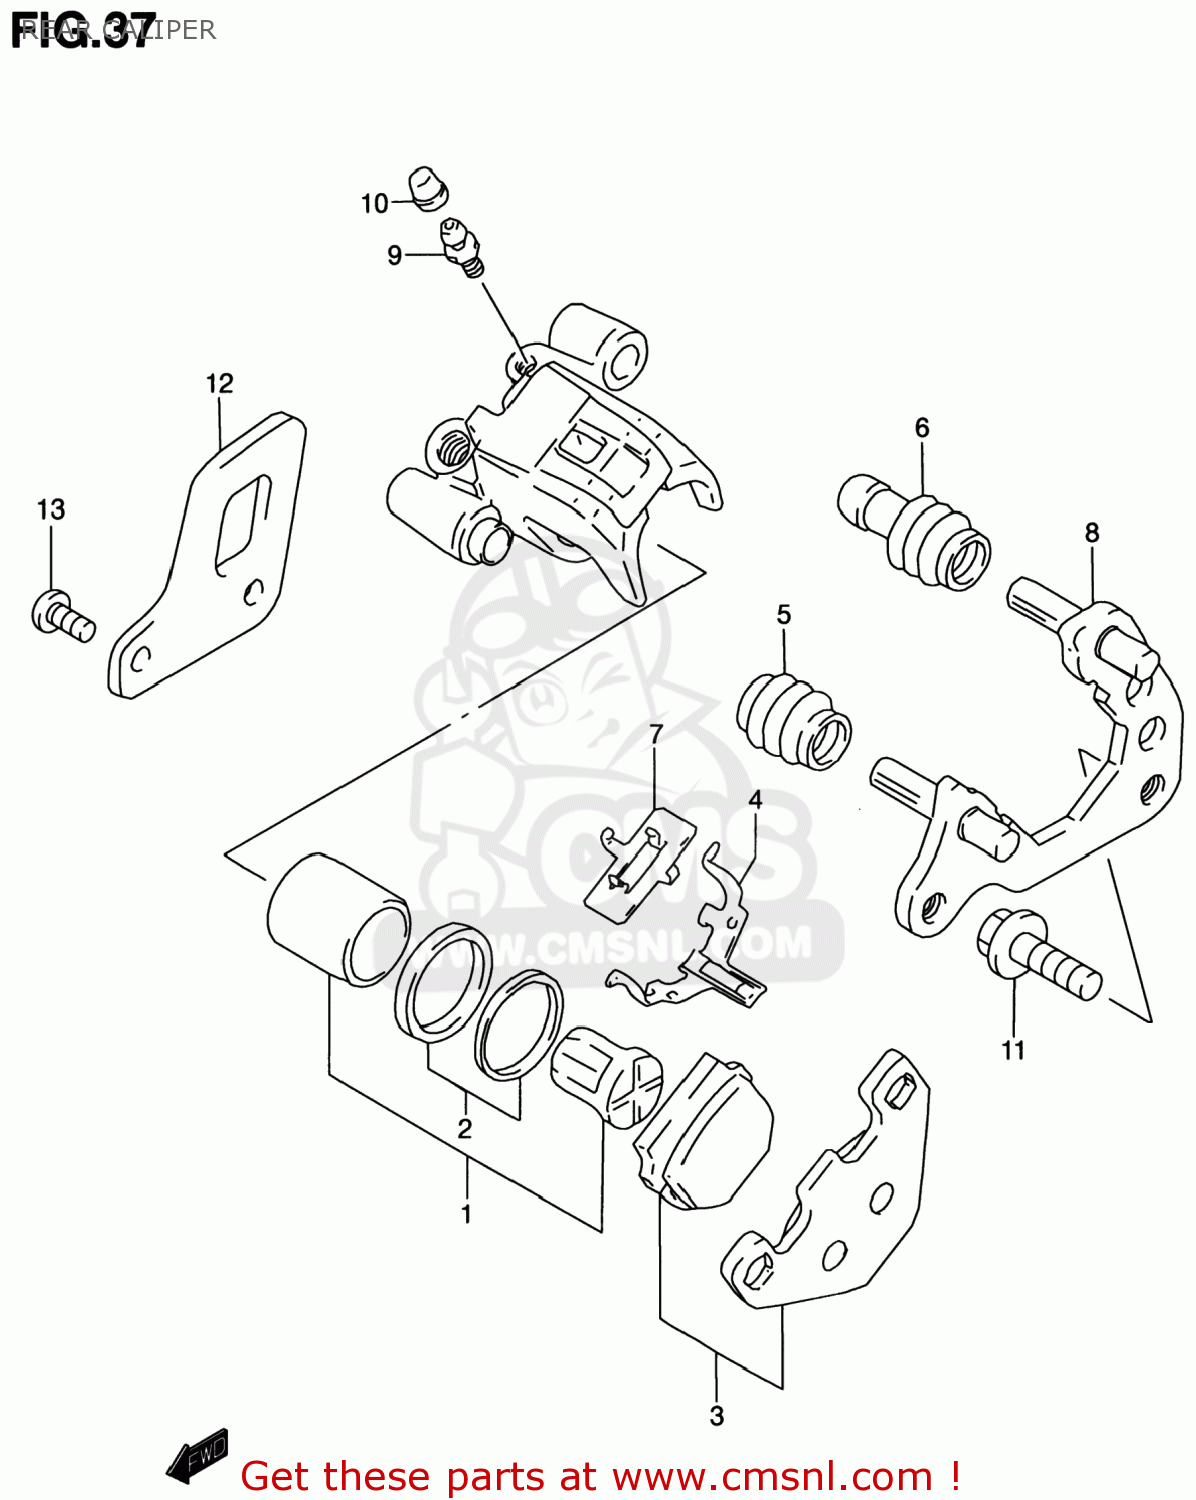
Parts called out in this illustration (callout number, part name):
1	PISTON SET
2	SEAL SET,PISTON
3	PAD SET (NAS)
4	SPRING,PAD
5	BOOT,AXLE
6	INSULATOR,AXLE
7	SHIM
8	CARRIER,CALIPER
9	BLEEDER
10	CAP,BLEEDER PLUG
11	BOLT(8X18)
12	GUARD,RR CALIPER
13	SCREW(6X12)
